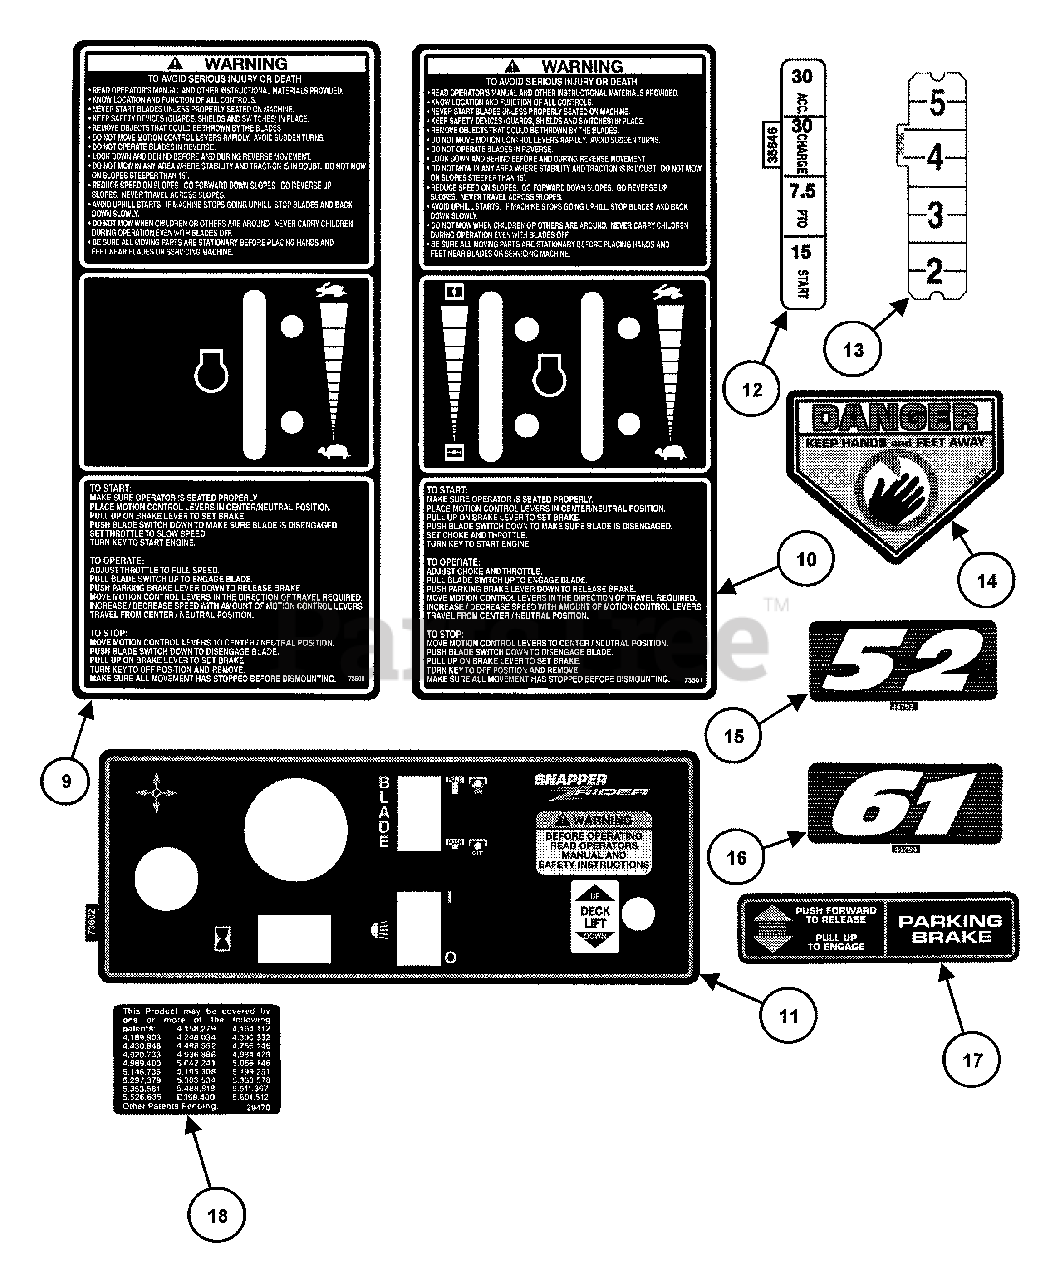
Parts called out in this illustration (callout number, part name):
9	DECAL, Throttle
10	DECAL, Throttle
11	DECAL, Instrument Panel
12	DECAL, Fuse
13	DECAL, Height-of-Cut
14	DECAL, Warning (CPSC Cut-Finger)
15	DECAL, Deck Size 52"
16	DECAL, Deck Size 61"
17	DECAL, Park Brake
18	DECAL, Patent Numbers
